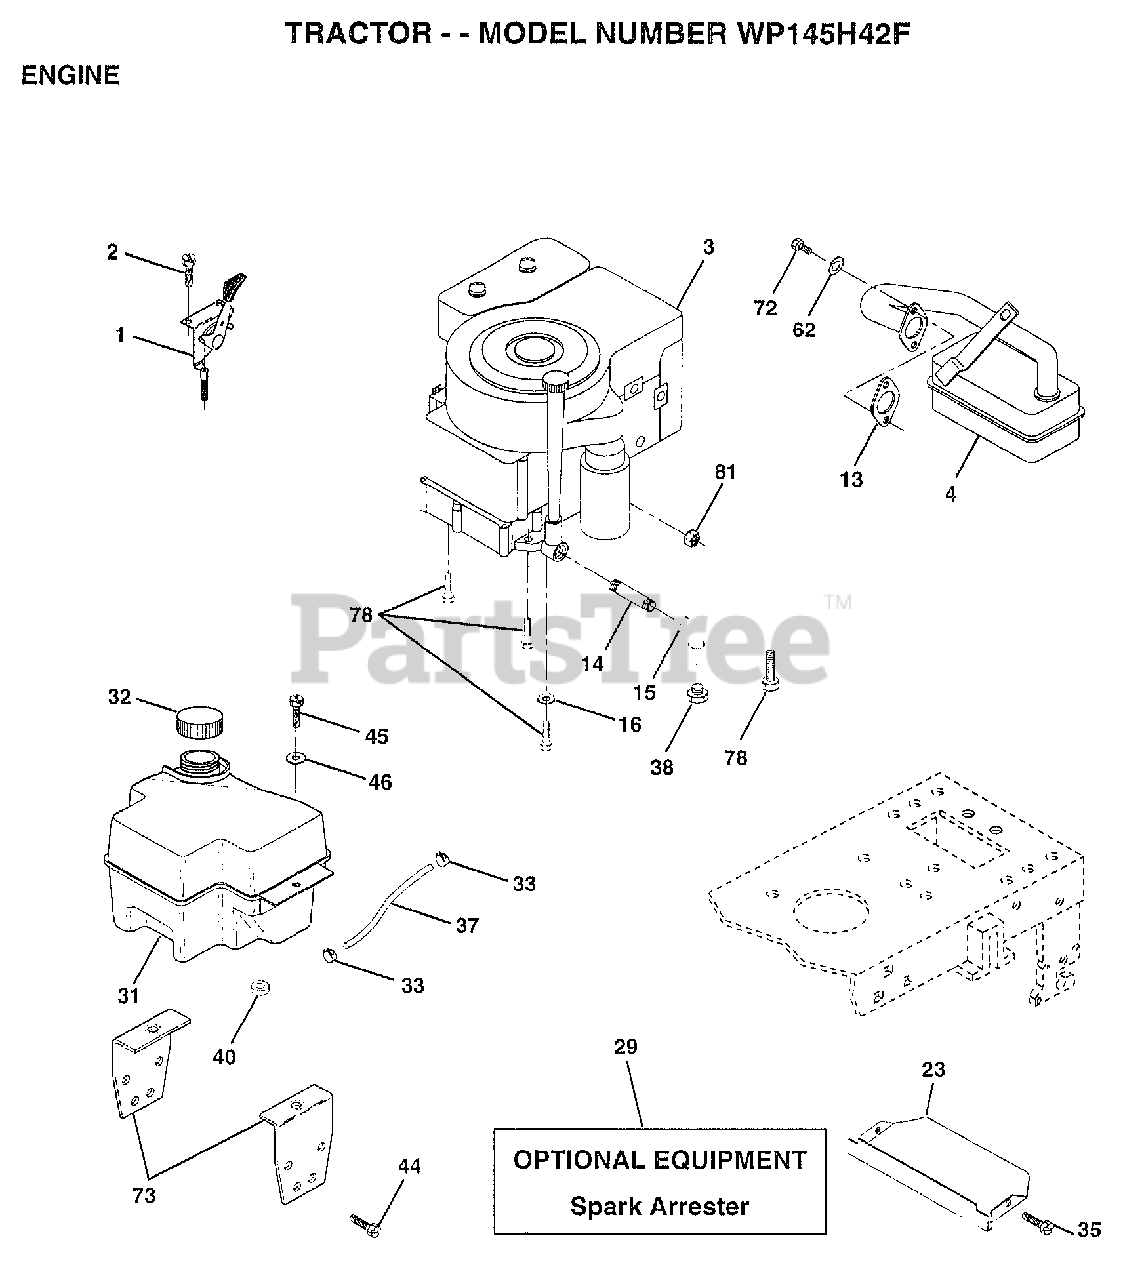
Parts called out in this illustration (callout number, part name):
1	"CONTROL,THROTTLE"
2	SCREW LT
4	MUFFLER
13	GASKET ENG 1 313 LD TIN PLATED
14	PIPE NIPPLE
15	ELBOW
16	LOCKWASHER
23	SHIELD.BRN/DBR.GD
31	TANK.FUEL.FRONT.
32	CAP ASM FUEL
33	HOSE CLAMP
35	SCREW
37	LINE FUEL
44	SCREW
45	SCREW HEX CRT
46	WASHER
62	LOCKWASHER
72	SCREW
73	BRACKET.SUPT.TANK
78	SCREW
81	NUT
